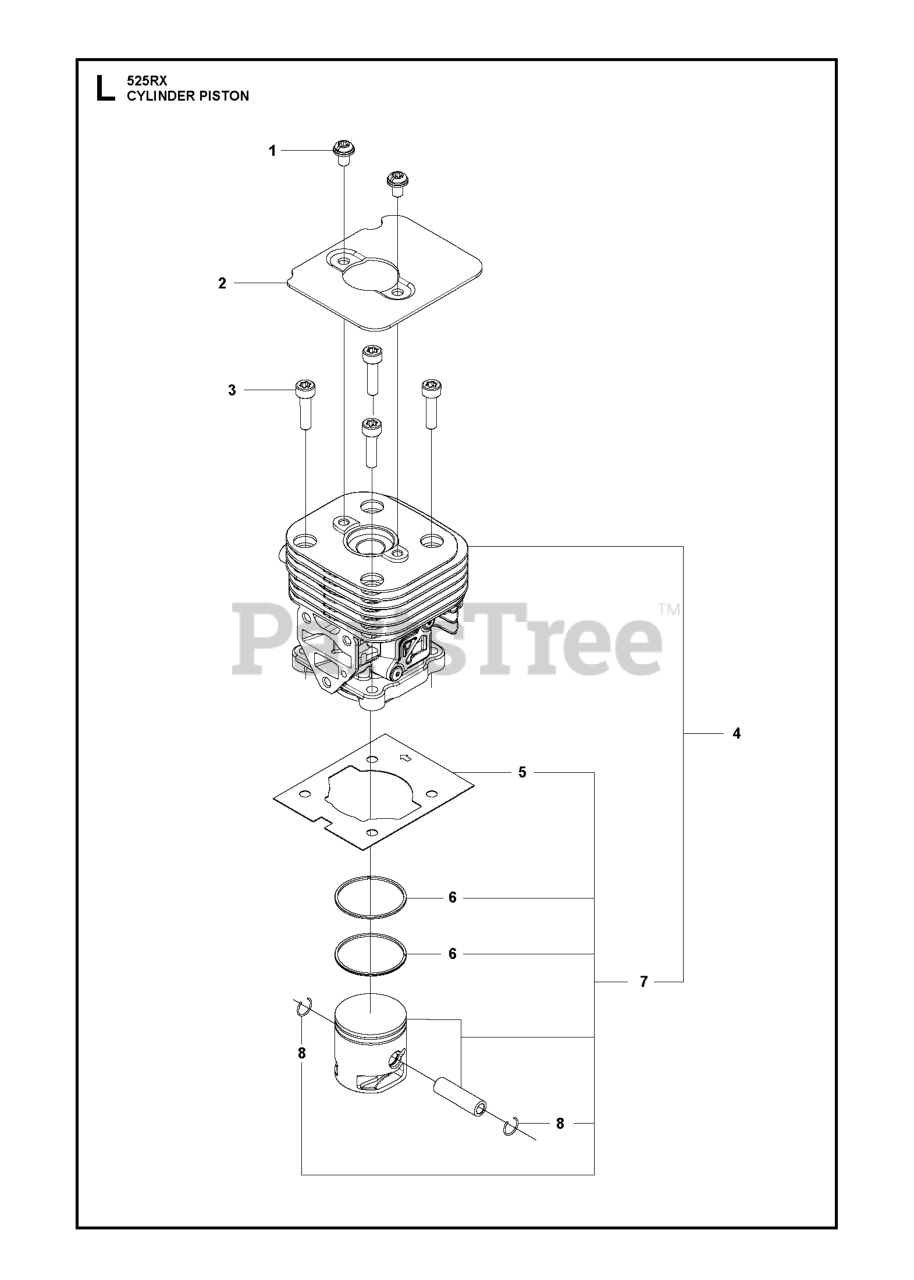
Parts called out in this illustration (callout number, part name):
2	PLATE CYLINDER
3	BOLT
4	SERVICE KIT
5	GASKET BASE
7	SERVICE KIT PISTON 525 TRIMMER
